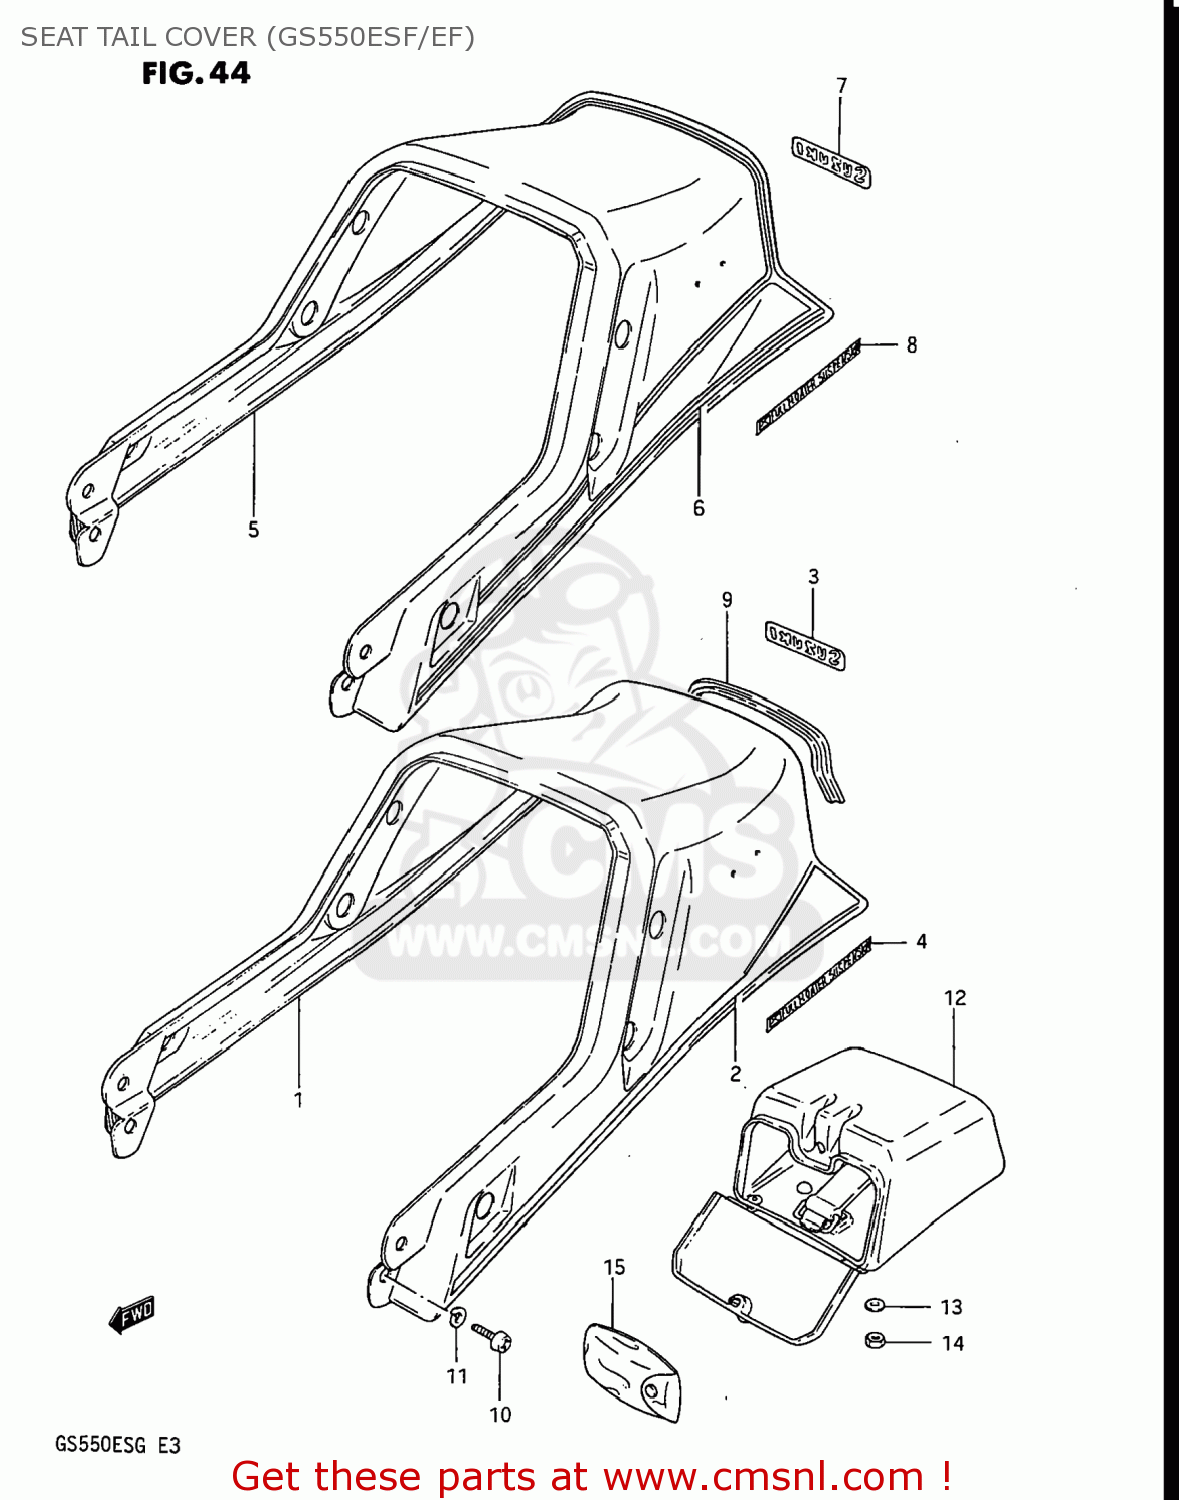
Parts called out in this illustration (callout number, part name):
1	COVER,SEAT TAIL
2	TAPE SET,SEAT TAIL COVER
3	EMBLEM(WHITE)
4	EMBLEM
5	COVER,SEAT TAIL
6	TAPE SET,SEAT TAIL COVER
7	EMBLEM(WHITE)
8	EMBLEM
9	BLIND,SEAT TAIL COVER
10	SCREW
11	LOCK WASHER
12	BOX,SEAT TAIL
13	WASHER
14	NUT
15	TOOL ASSY
